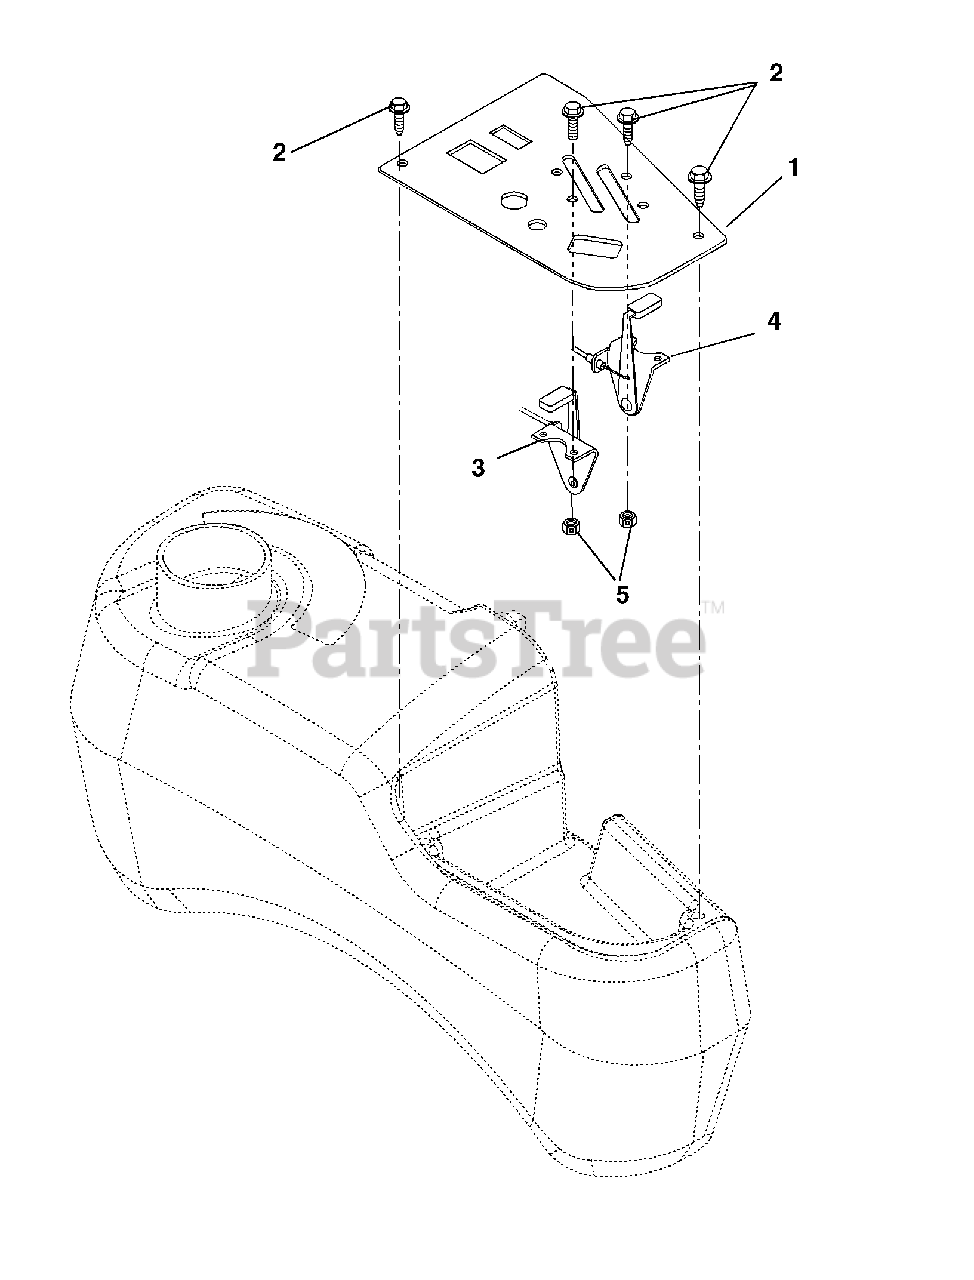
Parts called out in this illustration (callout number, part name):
1	CONTROL PANEL - BLACK
2	@SCR-MCH 10-24X.50 HWH YWZC
3	CABLE, THROTTLE
4	CABLE, CHOKE W/STR LEVER
5	@NUT-LK-NYL 10-24 W/INSRT YWZC
